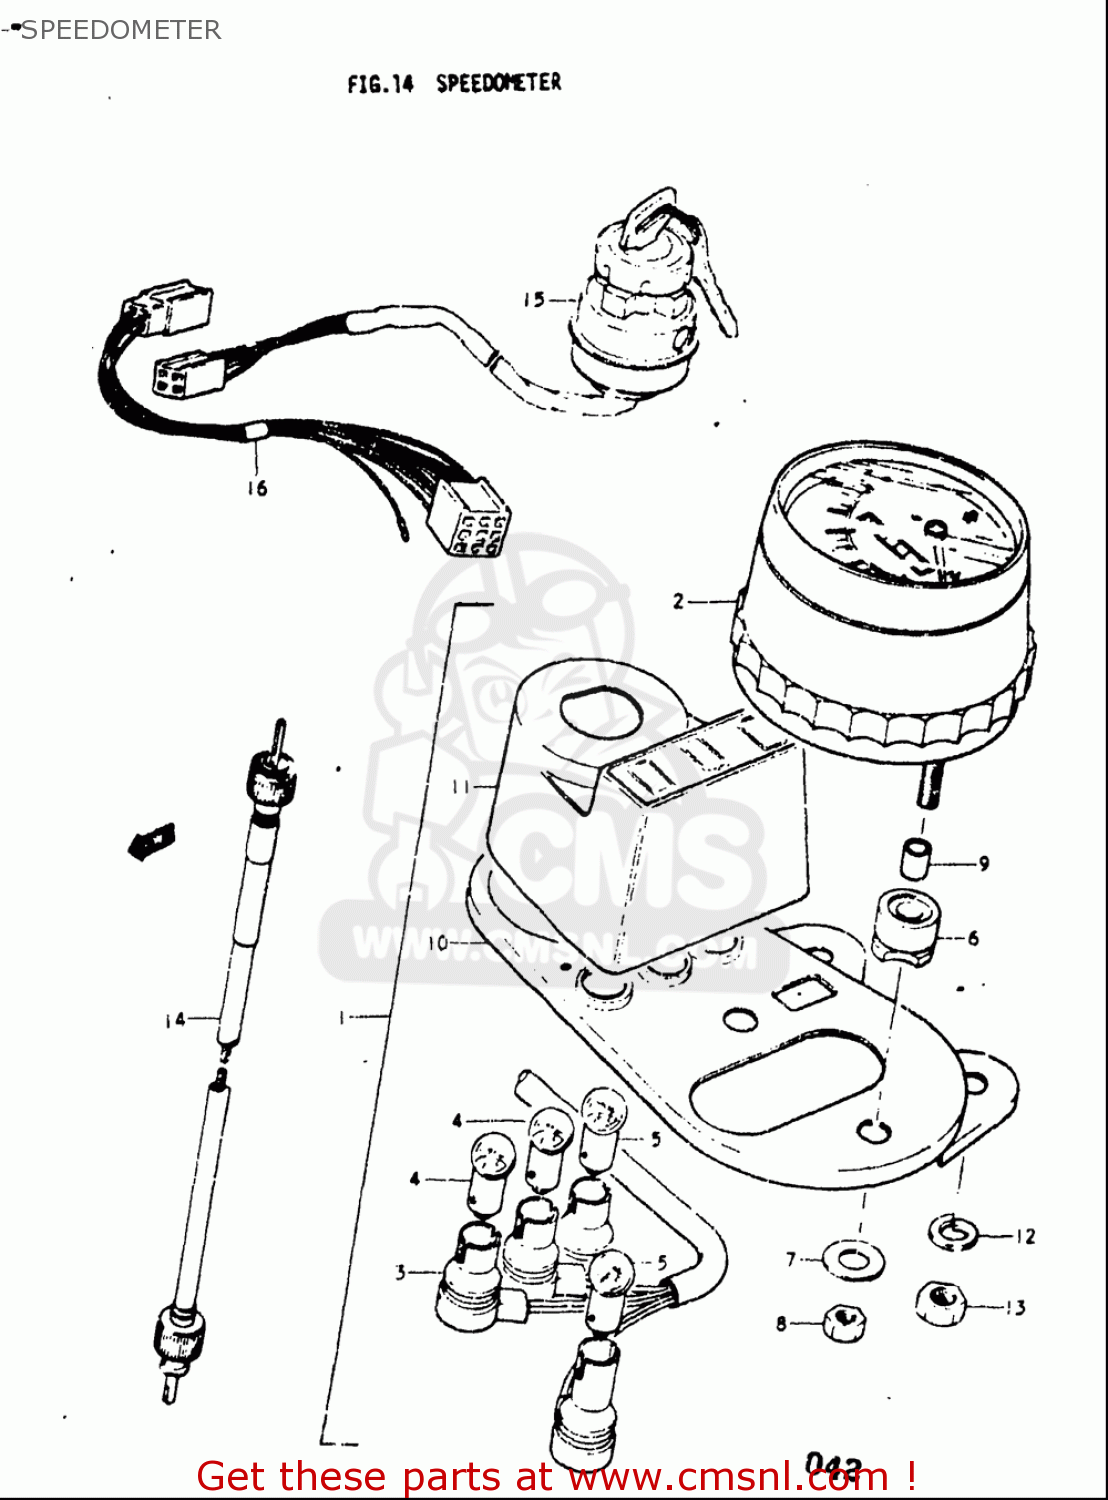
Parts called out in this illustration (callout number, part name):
3	SOCKET,SPEEDOMETER
4	BULB(6V1.7W,STANLEY,A61A)
5	BULB(6V/3W)
6	CUSHION,METER NO.1
8	NUT
11	CASE,PILOT BULB
12	WASHER,LOCK
13	NUT
14	CABLE ASSY,SPEEDOMETER
